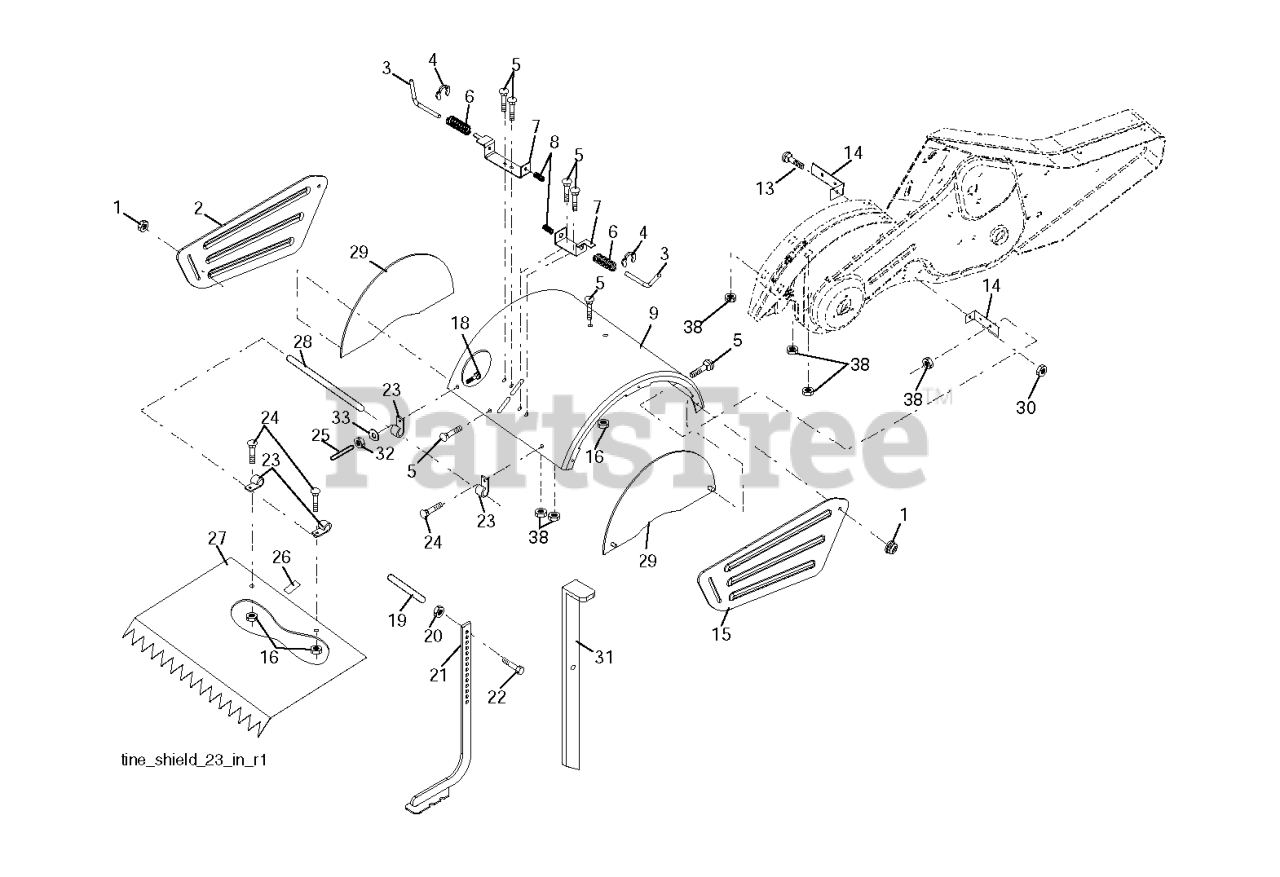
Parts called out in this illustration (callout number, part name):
1	NUT LOCK HEX FLANGE 5/16-18
2	SHIELD
3	STAKE PIN TI
4	RING, KLIP
5	BOLT, RDHD SQNK 5/16-18 X 3/4
7	BRACKET.LATCH.STAKE.3.20.BLACK
8	SPRING CRT
9	SHIELD.PNT.TINE.17"M
13	BOLT.CARRIAGE.5/16-18
14	BRACKET.TINE.SHIELD.TILLER
15	SIDE SHIELD RH
16	NUT T
20	NUT.HEX.3/8-16UNC
21	STAKE.DEPTH.16.CRT.BLACK
22	BOLT.375-16
26	PAD IDLER TI
27	SHIELD LEVELING
28	PIN.HINGE.TILLER
29	SHIELD.ASM.SIDE.ORANGE.(OLD)
30	LOCKNUT-FLANGE 5/16-18
31	RP.STAKE.DEPTH.DRAG.TILLR.GREY
32	NUT
33	LOCKWASHER
38	NUT
